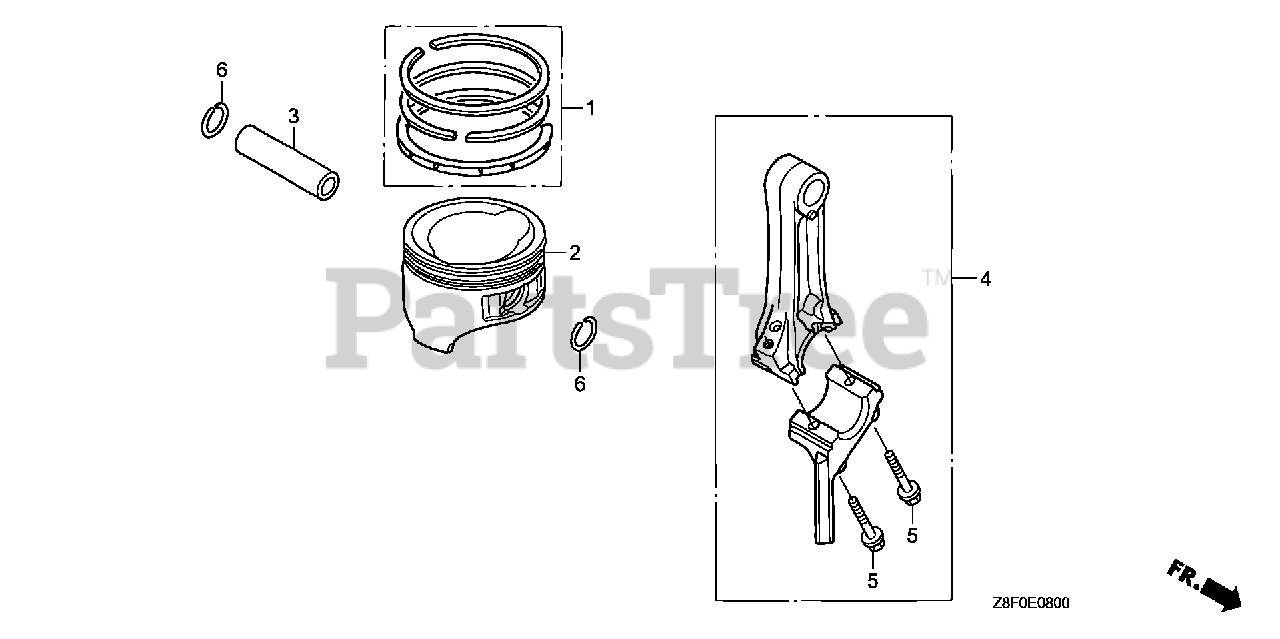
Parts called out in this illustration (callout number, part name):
1	RING SET, PISTON (STD) (TEIKOKU)
2	PISTON
3	PIN, PISTON
4	ROD ASSY., CONNECTING
5	BOLT, CONNECTING ROD
6	CLIP, PISTON PIN (13MM)
